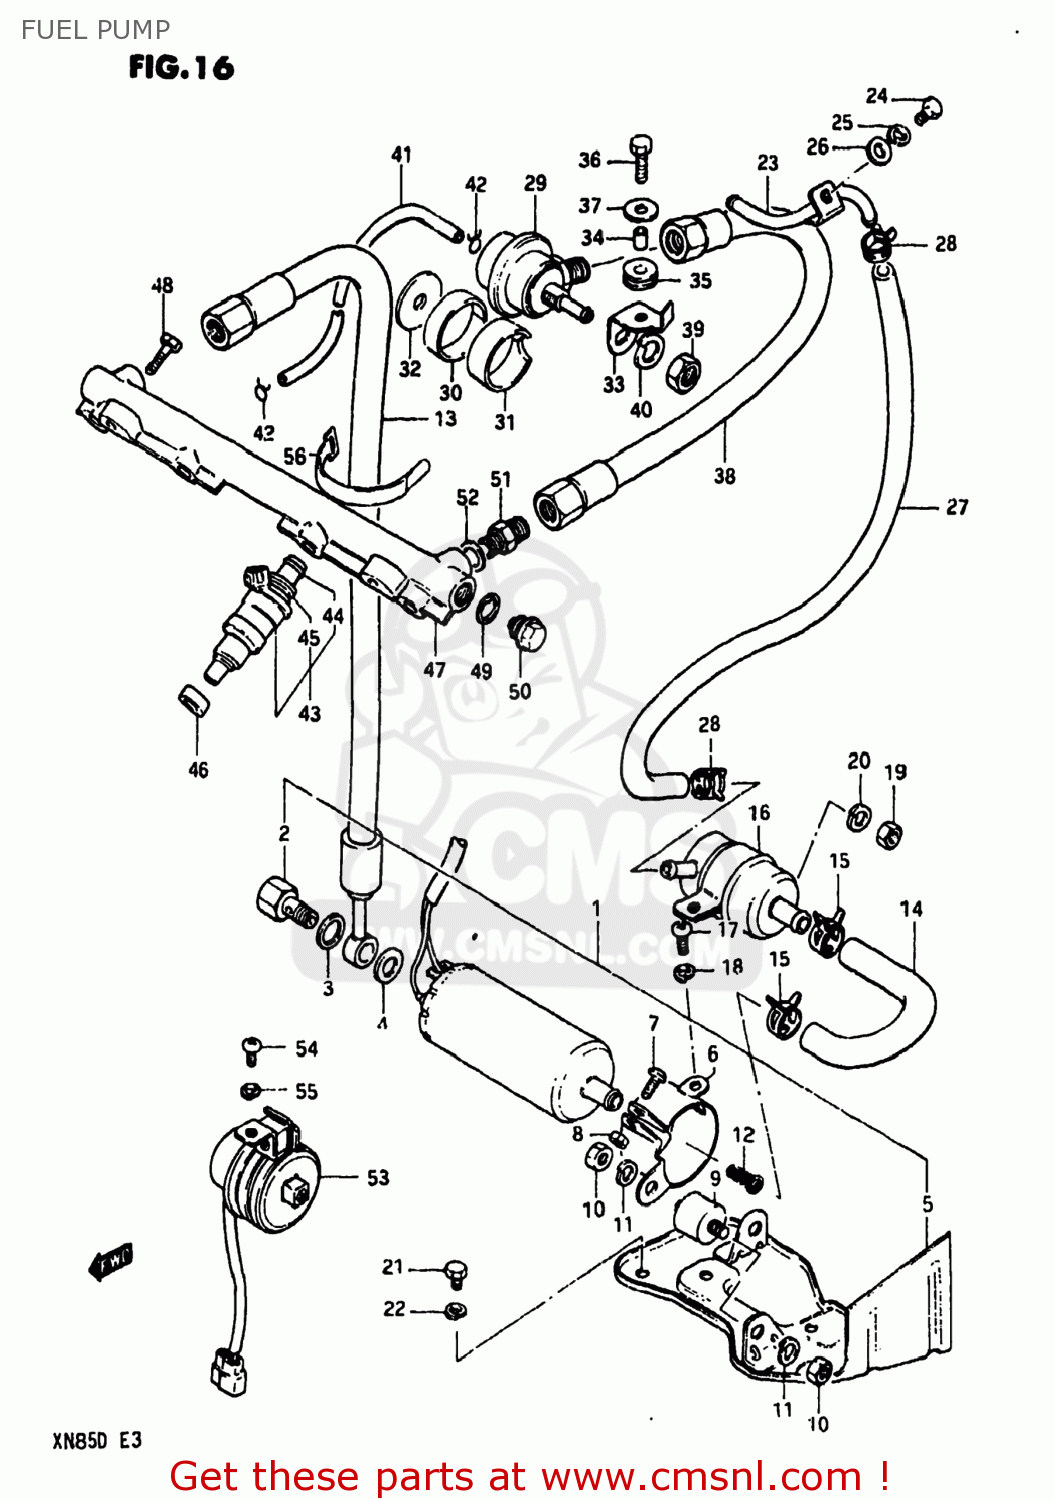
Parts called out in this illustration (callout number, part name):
1	PUMP ASSEMBLY,FUEL
2	NUT,FUEL PUMP
3	GASKET,FUEL PUMP
4	WASHER,FUEL PUMP
5	BRACKET,FUEL PUMP
6	CLAMP,FUEL PUMP
7	SCREW
8	NUT
9	CUSHION,FUEL PUMP
10	NUT
11	LOCK WASHER
12	FILTER
13	HOSE, OUTLET
14	HOSE,FUEL PUMP INLET N
15	CLAMP
16	FILTER ASSEMBLY,FUEL
17	SCREW 6X12
18	LOCK WASHER
19	NUT
20	LOCK WASHER
21	BOLT
22	LOCK WASHER
23	PIPE, PUMP INLET
24	BOLT
25	LOCK WASHER
26	WASHER
27	HOSE, PUMP INLET (2)
28	CLAMP
29	REGULATOR ASSEMBLY,FUEL PRESSURE
30	PROTECTOR,PRESSURE REGULATOR
31	PROTECTOR,PRESSURE REGULATOR
32	PROTECTOR,FUEL REGULATOR
33	BRACKET
34	SPACER(6.1X9X7.5)
35	CUSHION
36	BOLT
37	WASHER (6.5X20X1.2)
38	HOSE,FUEL PRESSURE REGULATOR
39	NUT 12MM
40	WASHER,LOCK 12
41	HOSE
42	CLAMP
43	INJECTOR ASSEMBLY,FUEL
44	O RING
45	GROMMET
46	SEAL RING,FUEL INJECTOR
47	HOLDER, INJECTOR
48	SCREW (6X25)
49	GASKET(14X20X1.5) (NAS)
50	PLUG(14X12)
51	BOLT UNION
52	GASKET(12X16.5X1.5) (NAS)
53	CONPENSATOR ASSEMBLY,ALTITUDE
54	SCREW
55	LOCK WASHER
56	CLAMP
